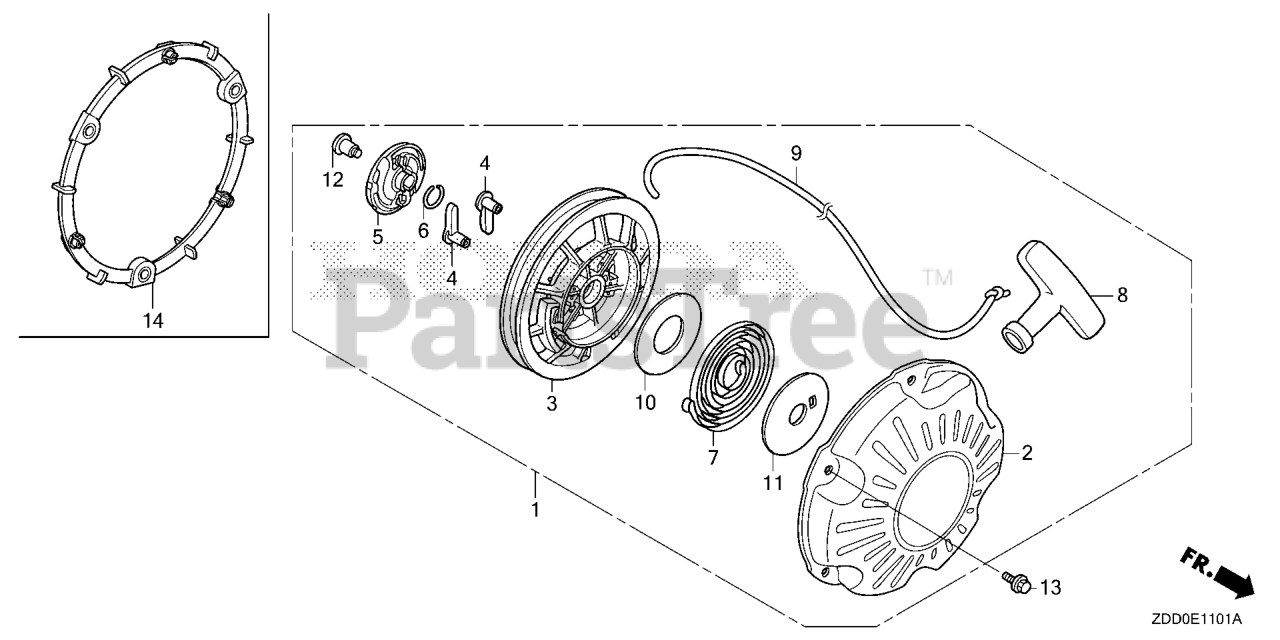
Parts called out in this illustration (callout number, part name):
1	STARTER ASSY., RECOIL *NH1* (BLACK)
2	CASE, RECOIL STARTER *NH1* (BLACK)
3	REEL, RECOIL STARTER (BLACK)
4	RATCHET, STARTER
5	GUIDE, RATCHET
6	SPRING, FRICTION
7	SPRING, RECOIL STARTER
8	KNOB, RECOIL STARTER
9	ROPE, RECOIL STARTER
10	PLATE, SIDE
11	PLATE, SLIDE
12	SCREW, SETTING (ENGINE NO.)
13	BOLT, FLANGE (6X8)
